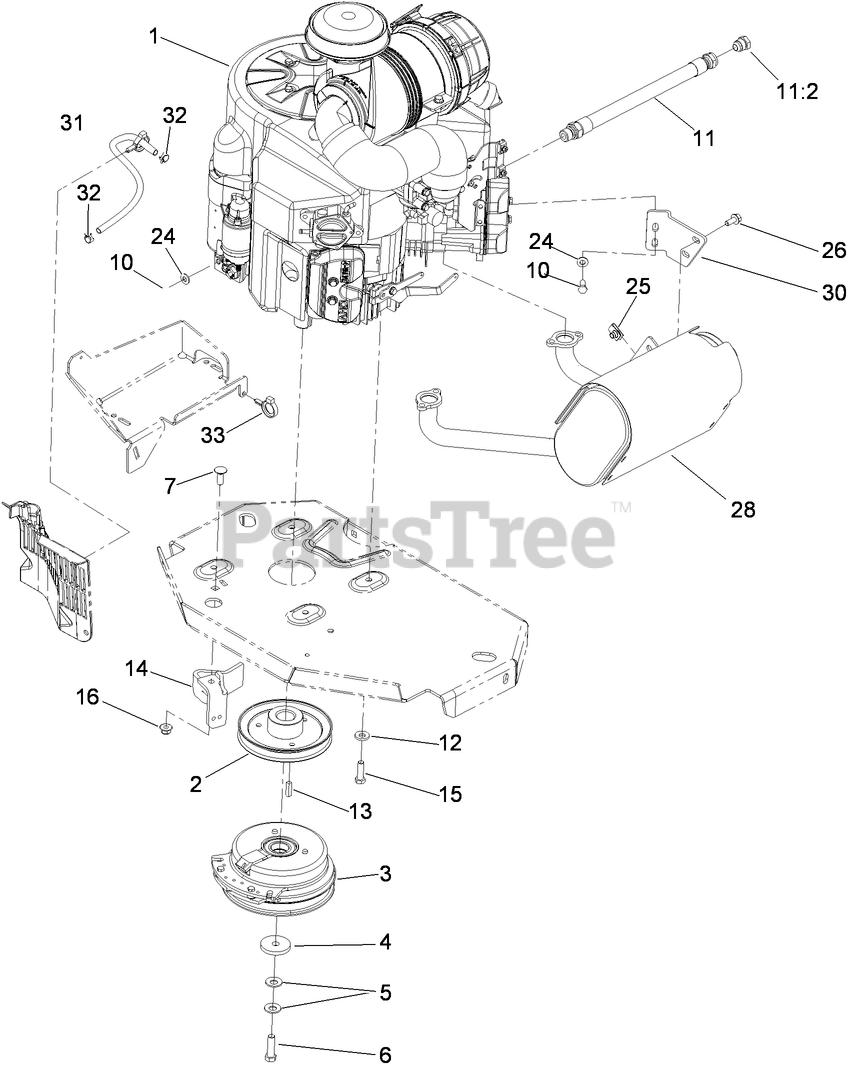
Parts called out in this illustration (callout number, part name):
2	SHEAVE
3	CLUTCH KIT
4	WASHER-CLUTCH
5	WASHER-SPRING
6	SCREW-HH, W/LOCTITE
7	SCREW-CARR
10	SCREW-HH
11	OIL DRAIN HOSE ASM
12	WASHER-BELLEVILLE
14	CLUTCH-ANCHOR
15	SCREW-HH
16	NUT-HF, NI
24	WASHER-SPRING
25	NUT-U
26	SCREW-HHF
28	MUFFLER
30	BRACKET-MUFFLER
31	HOSE-FUEL
32	CLAMP-HOSE
33	CLAMP-HOSE
